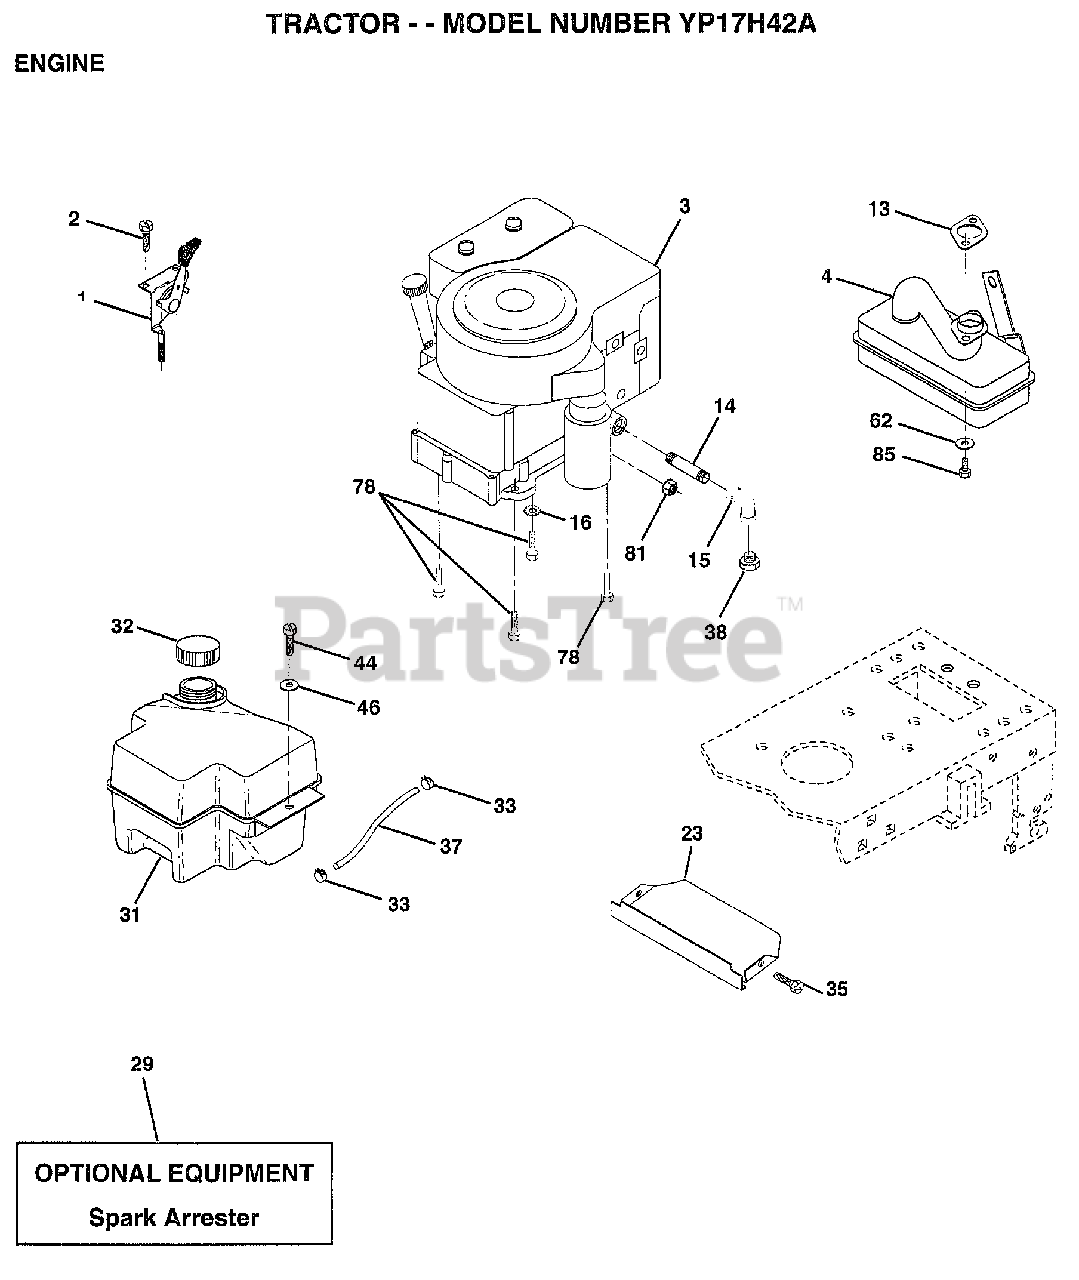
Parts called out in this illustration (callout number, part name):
1	CONTROL THROTTLE
2	SCREW LT
4	MUFFLER
13	GASKET MUFFLE TEC
14	PIPE NIPPLE LT
15	ELBOW
16	LOCKWASHER
23	SHIELD.BRN/DBR.GD
31	TANK.FUEL.FRONT.
32	CAP ASM FUEL
33	HOSE CLAMP
35	SCREW
37	LINE FUEL
44	SCREW HEX CRT
46	WASHER
62	LOCKWASHER
78	SCREW
81	NUT
85	SCREW HEX HD CAP
